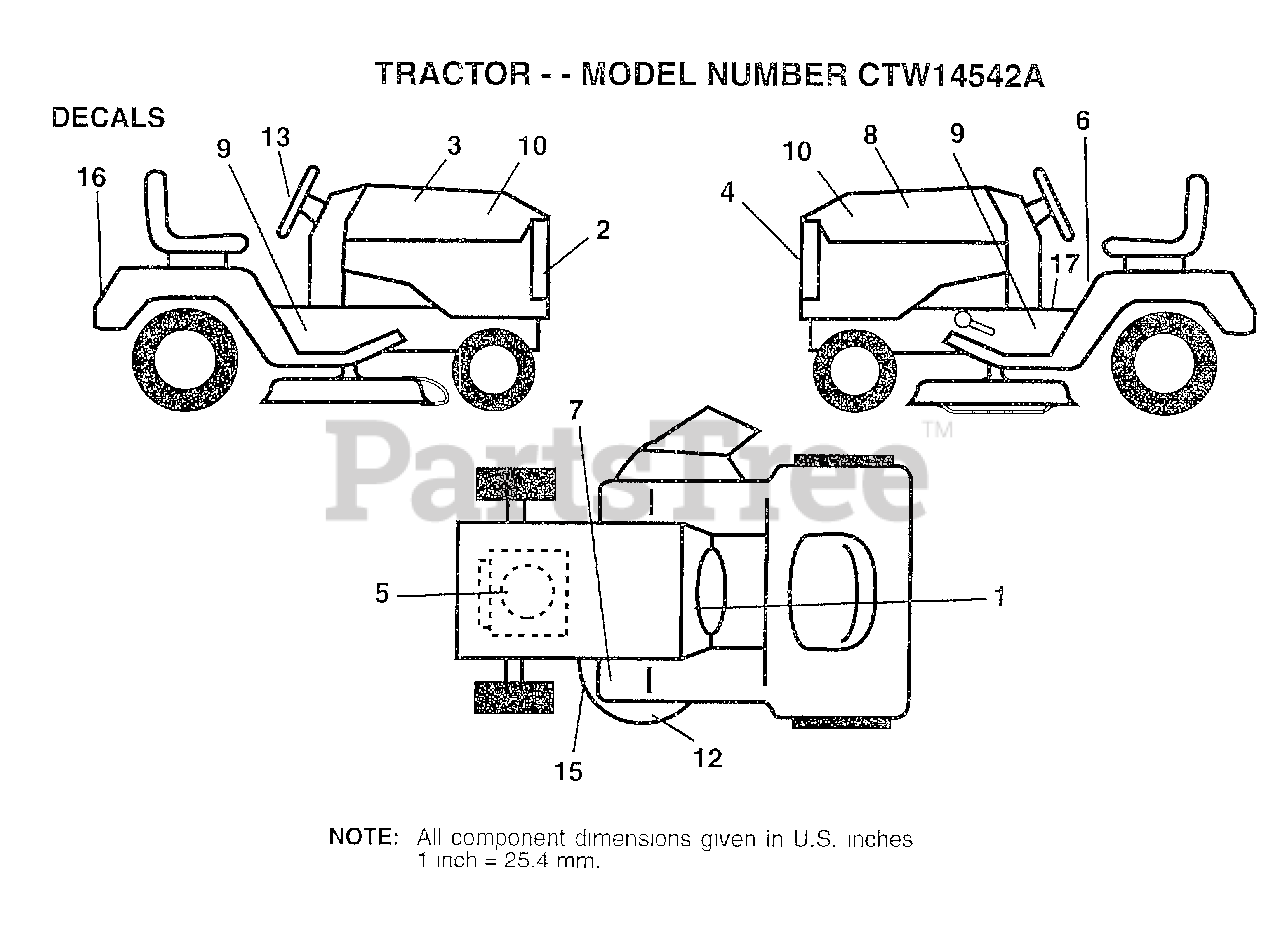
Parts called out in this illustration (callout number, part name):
1	DECAL.DASH.INST.
2	DECAL.GRILLE.RALY
3	DECAL.HD.RH.
5	DECAL, ENGINE
6	DECAL
8	DECAL.HD.LH
9	CHASSIS DECAL
10	DECAL.INS.HD.RALL
13	DECAL.WHEEL.STEER
15	DECAL
16	DECAL.FENDER.
17	DECAL BRAK PARK
